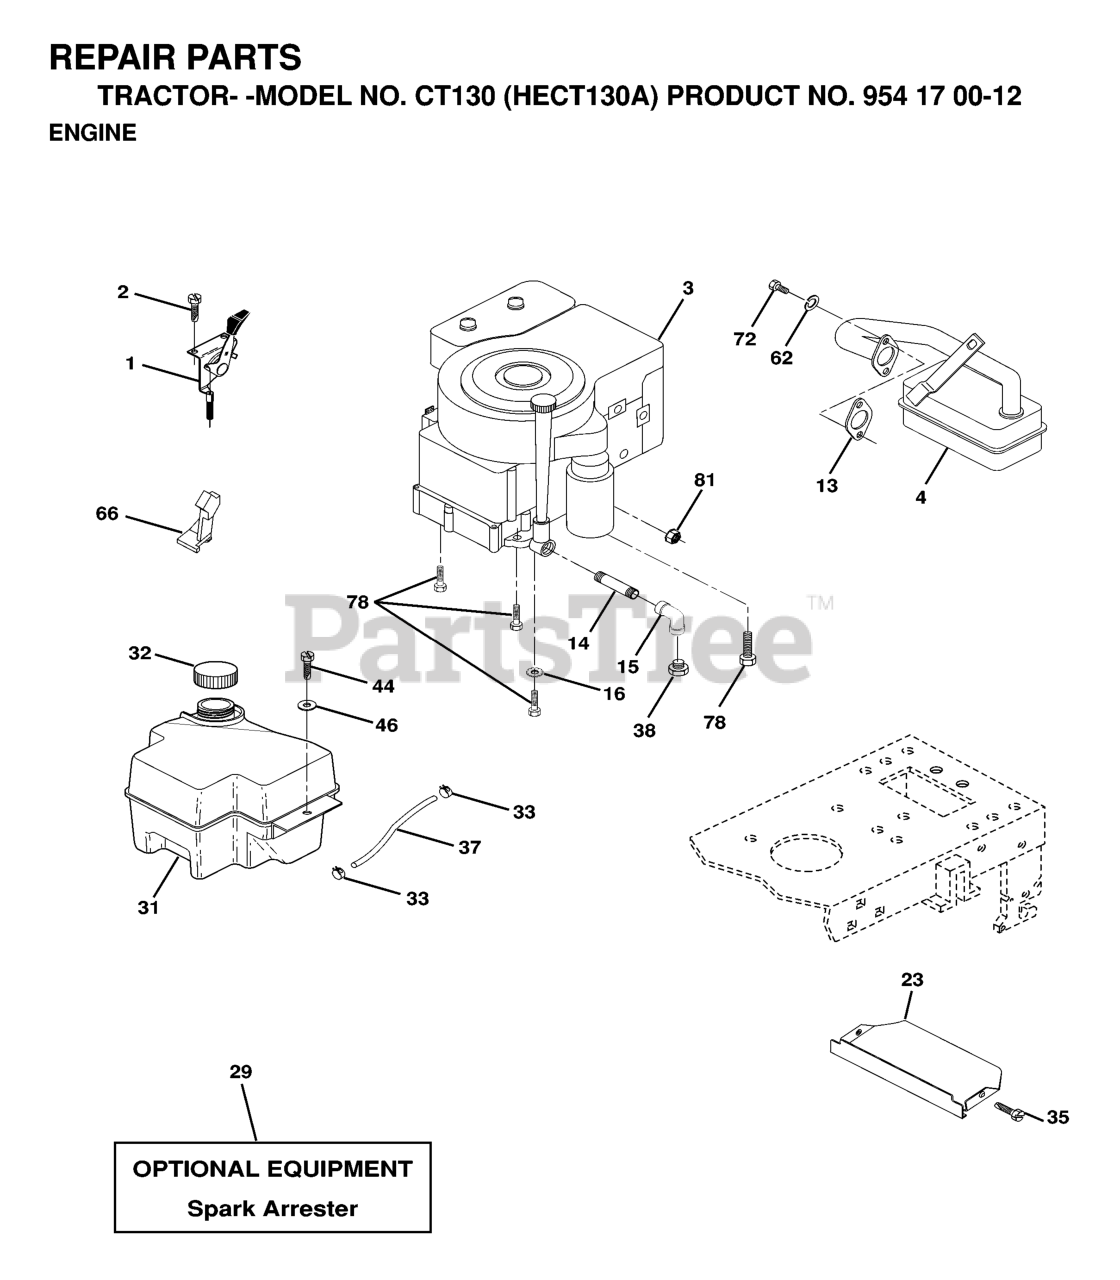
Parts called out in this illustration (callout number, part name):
1	CONTROL
2	SCREW LT
4	MUFFLER.LT.BRIGGS.14HP.IC/OHV
13	REPL BY 532 27 22-93
14	Nipple Pipe 3/8 Npt X 3-1/2
15	ELBOW
16	LOCKWASHER
29	KIT.SPARK ARRESTOR 794945 B&S
31	FUEL TANK
32	FUEL CAP
33	HOSE CLAMP
35	SCREW.THDROL.5/16-18X3/4.TTY
37	LINE.FUEL.20
44	SCREW HEX CRT
62	WASHER.LOCK.HVY.HLCL.SPR.5/16
66	STOP THROTTLE
72	SCREW
78	SCREW
81	NUT FLANGE 1/4-20 STARTER NUT
